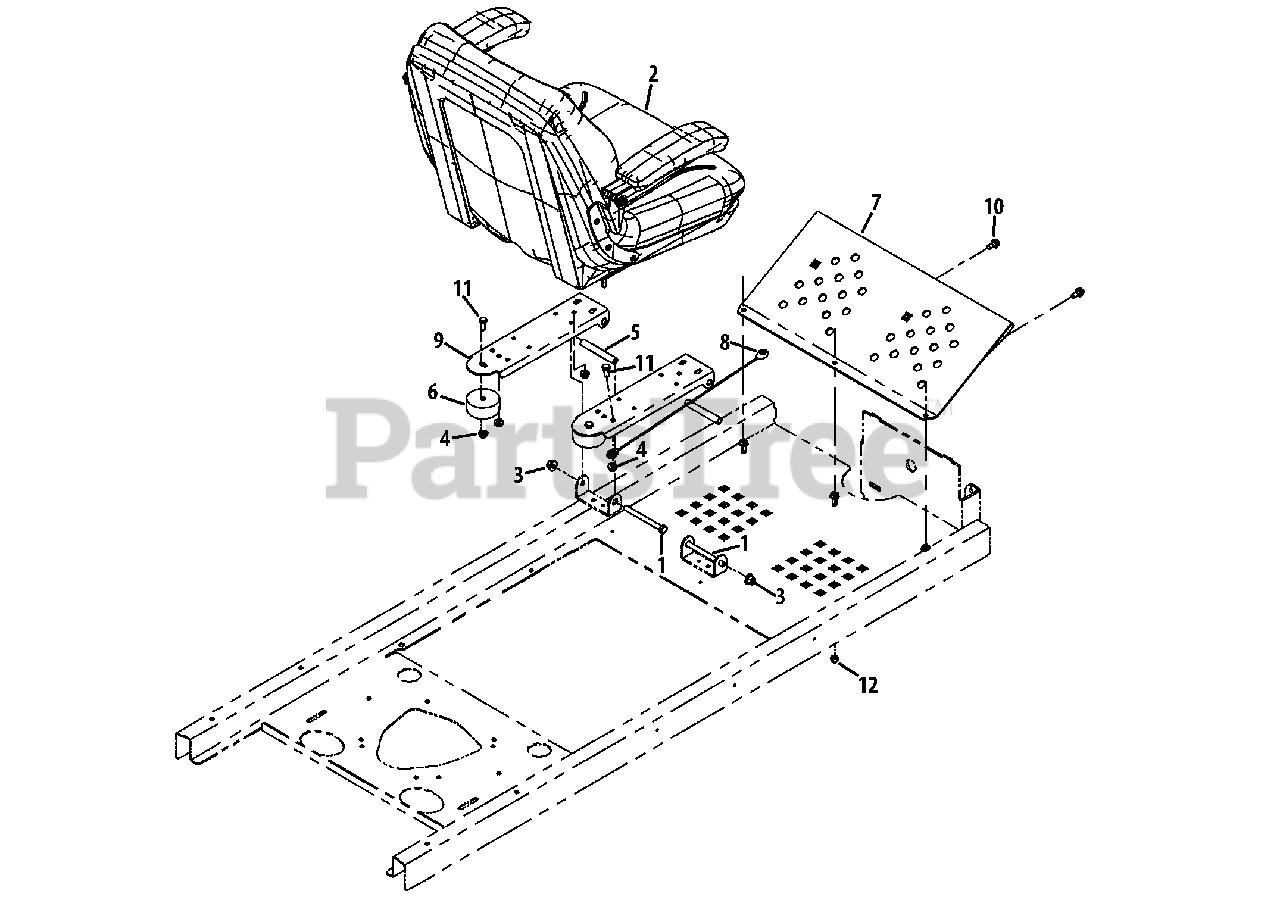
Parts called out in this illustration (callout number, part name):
1	Hex Cap Screw, 3/8-16 x 4.00
2	Seat
3	Counterlock Flange Nut, 3/8-16
4	Nut, 5/16-18, Centerlock
5	Spacer, .370 ID x .500 x 3.45
6	Bumper, 2.50 x 1.13
7	Foot Rest Bracket
8	Lift Cable
9	Seat Mounting Bracket
10	Self Tapping Screw 5/16-18 x .750
11	Hex Cap Screw, 5/16-18 x .75
12	Nylock Nut, 5/16-18
